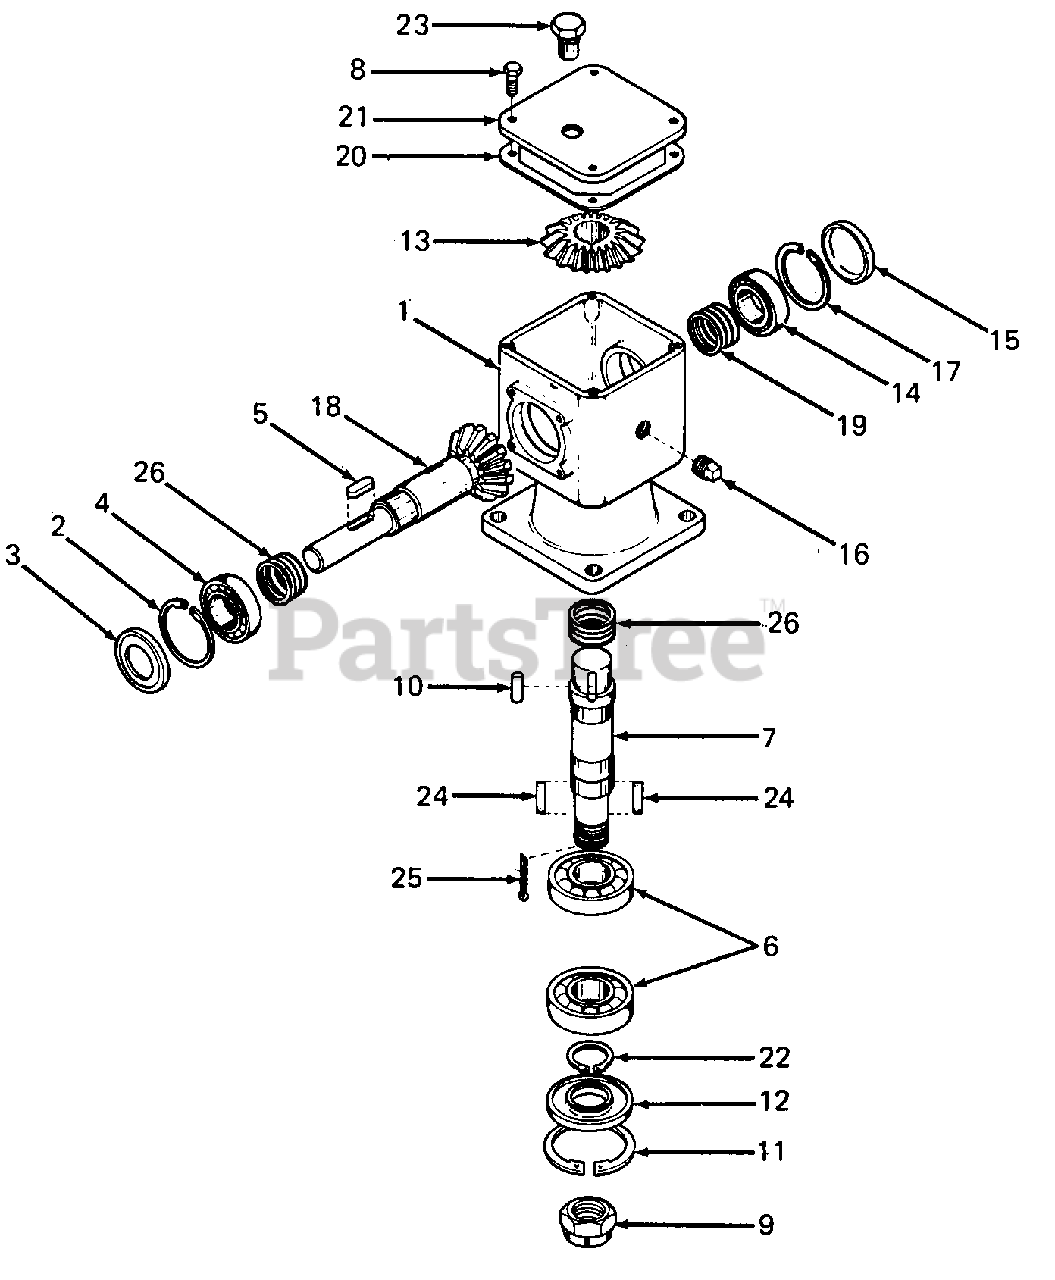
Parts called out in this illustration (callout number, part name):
2	Ring, Snap
3	Seal, Oil
4	Bearing
6	Bearing, Lower
8	Bolt, M8 X 16 mm
9	Nut, Castle
11	Ring, Snap
12	Seal, Lower Oil
17	Ring, Snap
18	Shaft, Pinion
19	Shim, .3 mm
22	Ring, Snap
25	Pin, Cotter
26	Shim, .3 mm
